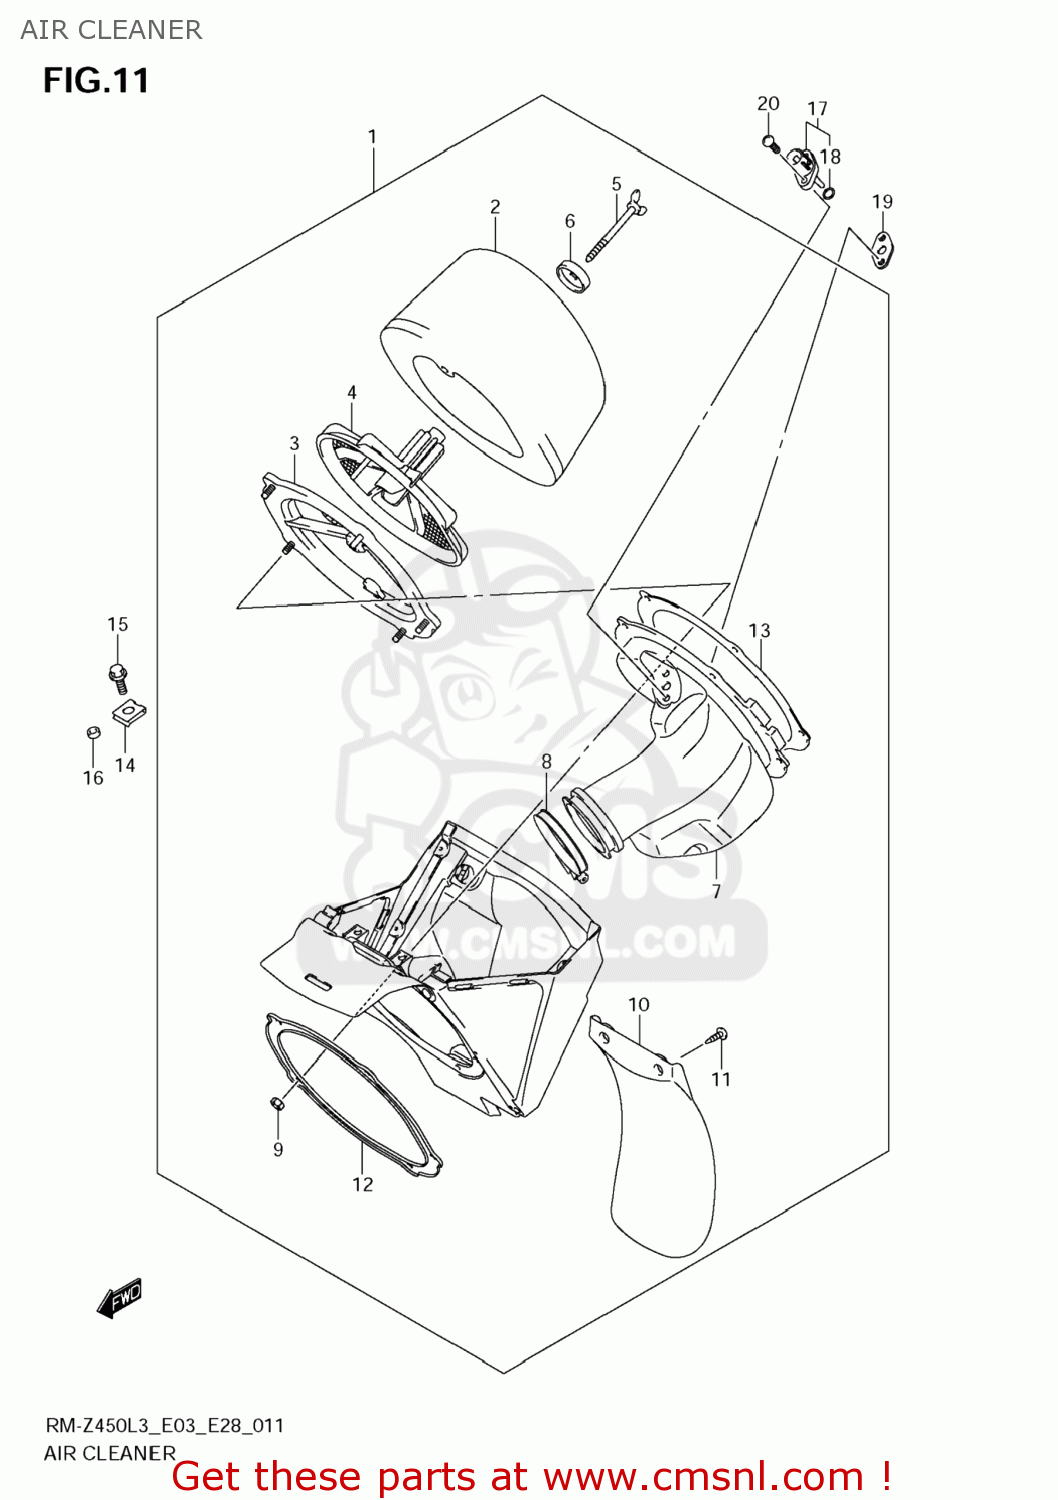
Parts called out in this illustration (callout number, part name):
1	CLEANER ASSY,AIR
2	FILTER ASSY
3	BASE,FILTER
4	HOLDER,FILTER
5	BOLT,WING
6	WASHER,AIR CLEANER
7	TUBE,OUTLET
8	CLAMP,THROTTLE BODY SIDE
9	NUT
10	MUDGUARD
11	SCREW
12	PLATE
13	GASKET (NAS)
14	NUT
15	BOLT
16	SPACER(6.2X10X2.2)
17	SENSOR,AIR TEM
18	O RING
19	BRACKET,AIR TEMP SENSOR
20	SCREW
